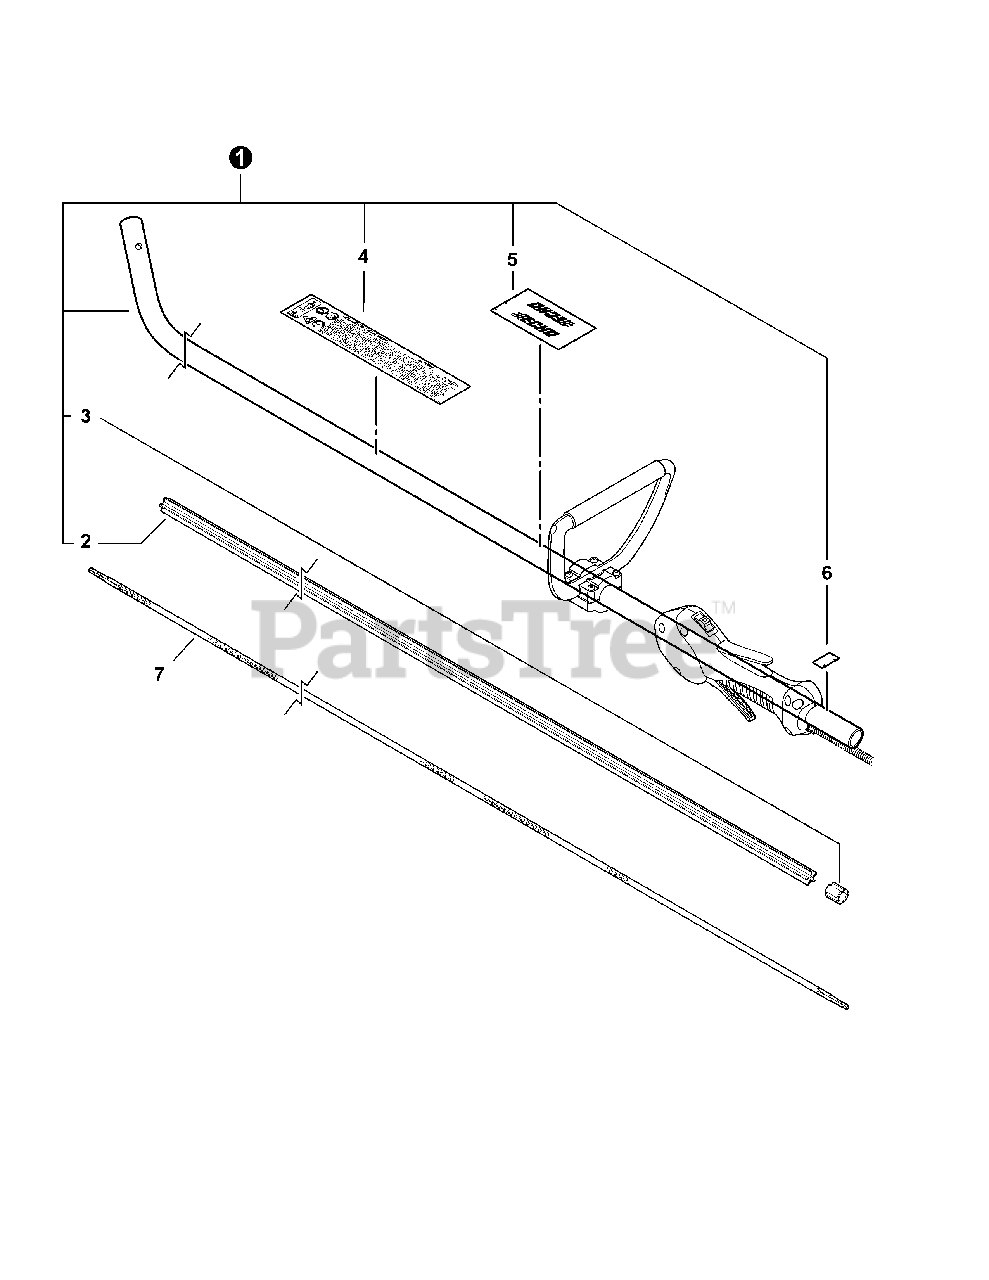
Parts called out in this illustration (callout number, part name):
1	MAIN PIPE ASY
2	LINER - FLEXIBLE
4	LABEL - CAUTION
5	LABEL - HANDLE LOCATION
6	LABEL - ALIGNMENT
7	DRIVESHAFT - FLEXIBLE
